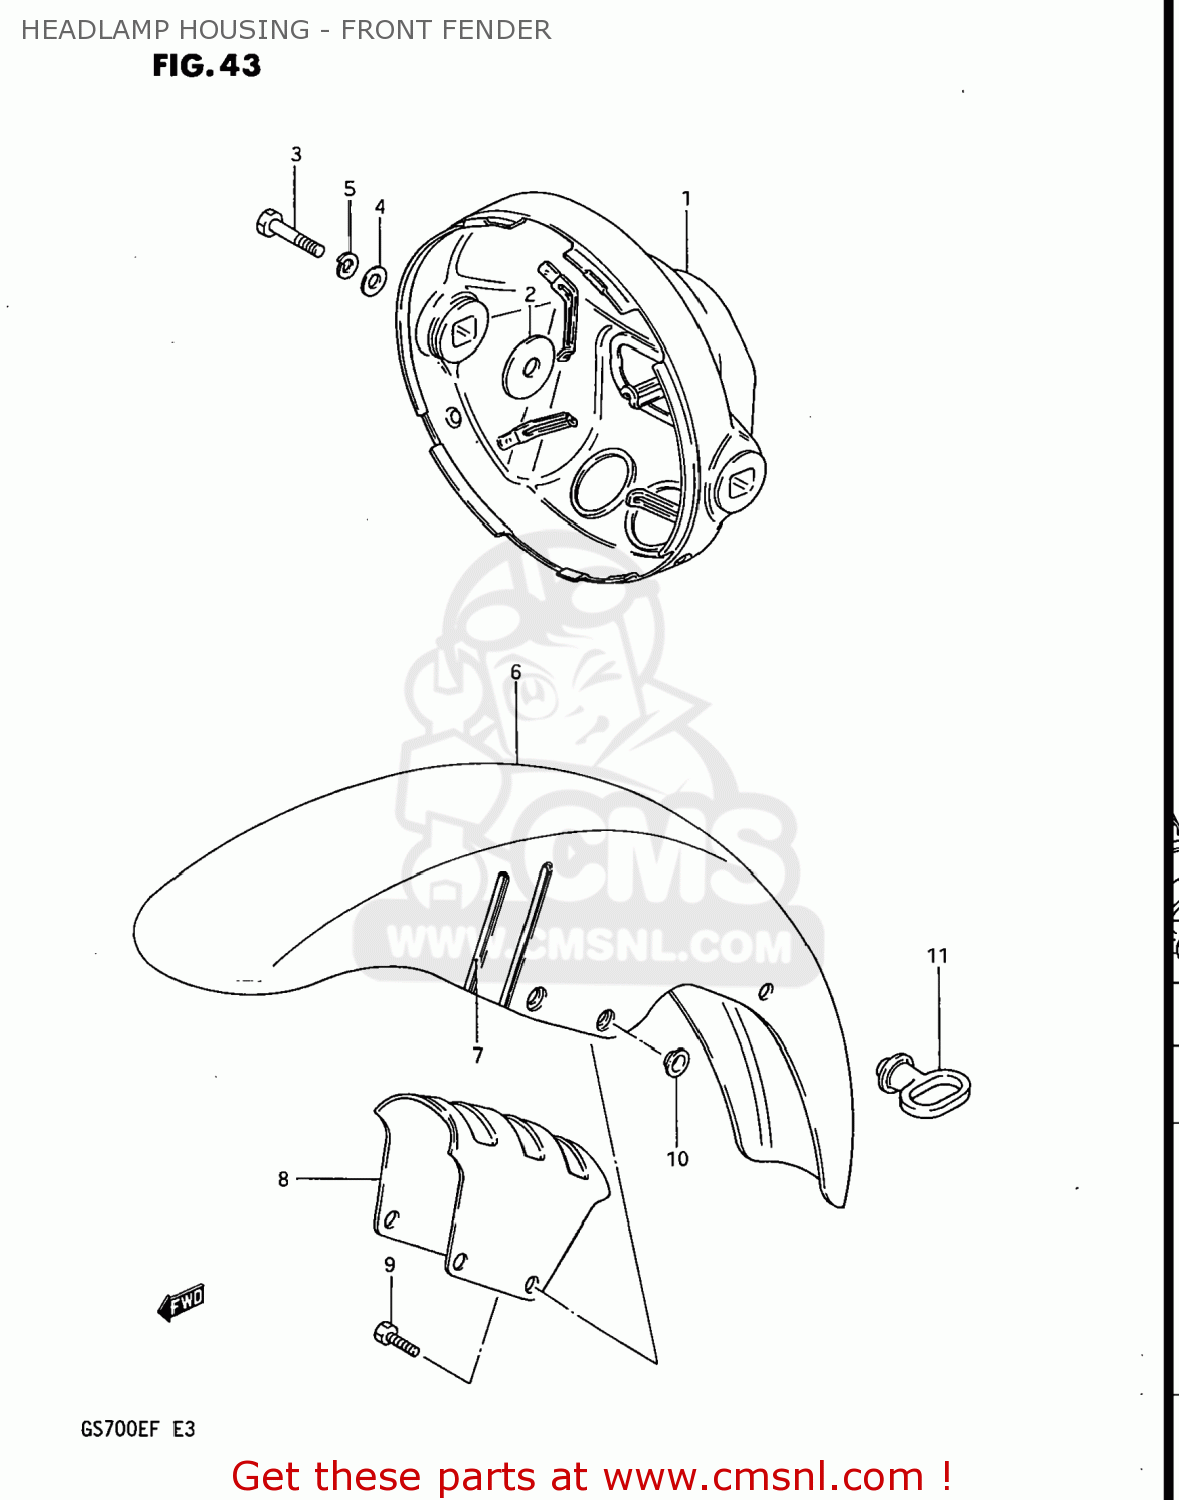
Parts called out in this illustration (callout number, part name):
1	HOUSING,HEADLAMP(BLACK)
2	WASHER (8.5X29X1.6)
3	BOLT
4	WASHER
5	LOCK WASHER
6	FENDER,FRONT
7	DENT,FRONT FENDER
8	BRACE,FRONT FENDER
9	BOLT
10	WASHER
11	GUIDE,CABLE
